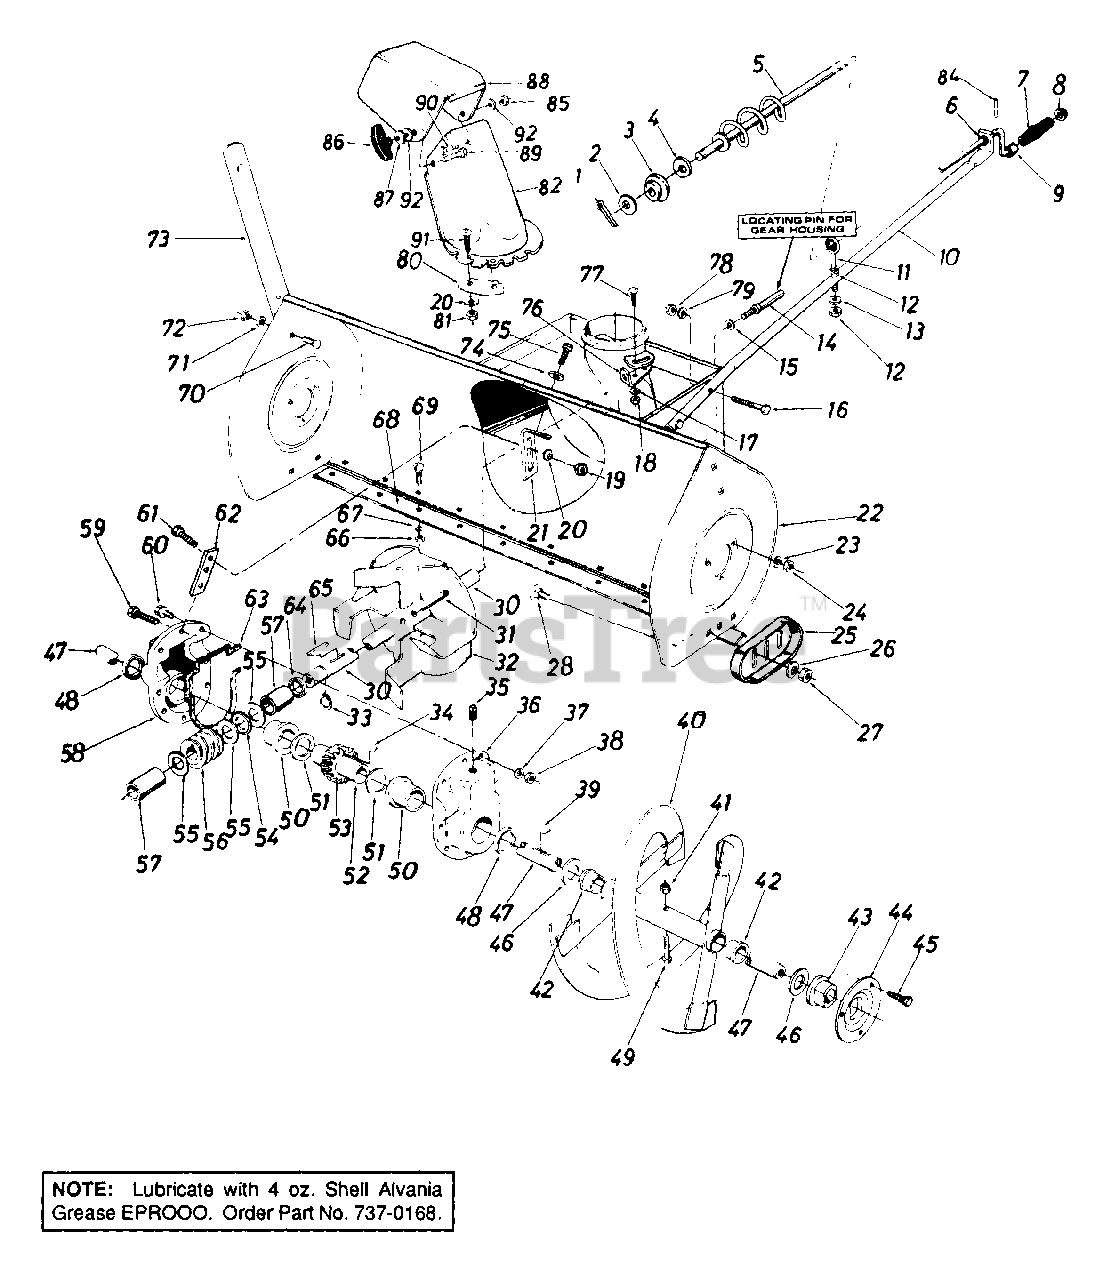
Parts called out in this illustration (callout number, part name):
1	Cotter Pin
2	Fl-Wash..39" I.D. x.62" O.D.
3	Plastic Bushing
4	Fl-Wash..385" I.D. x .62" O.D.
5	Chute Crank Ass'y.
6	Plastic Bushing
7	Knob (Black)
8	Push Nut 3/8" Rod
9	Spacer .385 I.D. x .50" I.D.
10	Chute Crank Support Tubing
11	Eyebolt
12	Hex Nut 5 16-18 Thd.
13	Bell-Wash..345" I.D. x.88" O.D.
14	Stud 3/8-16 x 2.75" Lg.
15	Bell-Wash..400" I.D. x .88" O.D.
16	Hex Bolt 3/8-24 x 1.25" Lg.
17	Bell-Wash..345" I.D. x .88" O.D.
18	Hex Nut 5/16-18 Thd.
19	Hex Nut 1/4-28 Thd.
20	Bell-Wash..265" I.D. x.75" O.D.
22	45" Snow Blower Housing Ass'y.
23	L-Wash. 5/16" I.D.
24	Hex Nut 5/16-18 Thd.
25	Slide Shoe
26	Bell-Wash..400" I.D. x .88" O.D.
27	Hex Jam Nut 3/8-16 Thd.
28	Carriage Bolt 3/8-16 x .62" Lg.
30	Blower Axle .875" Dia. x 14.75" Lg.
31	Spring Pin Spir. 5/16" Dia. x 1.75" Lg.
34	#91 Woodr-Key 1/4 x 3/4" Dia. (HDN)
35	Vent Plug
36	Comp. Gear Hsg. Half-L.H.
37	Spr-Wash..32" I.D. x .62" O.D.
38	Hex Ins. L-Nut 5/16-18 Thd.
39	#91 Woodr-Key 1/4 x 3/4" Dia. (HDN)
41	Hex ins. L-Nut 5/16-18 Thd.
42	Plastic Bushing
43	Flange Brg. w/flats 1" I.D.
44	Bearing Housing
45	Hex Sems Bolt 5/16-18 x .75" Lg.
46	Fl-Wash. 1.00" I.D. x 1.75" O.D.
47	Spiral Axle
48	Flange Bearing 1.503" I.D.
49	Shear Bolt 5/16-18 x 1.75" Lg.
50	Oil Seal 1.50" I.D.
51	Fl-Wash. 1.50" I.D. x 2.00" O.D.
52	Worm Gear Shaft
53	Double Threaded Worm Gear-L.H.
54	Thrust Brg. - 88" I.D. x 1.44" O.D.
55	Fl-Wash. .88" I.D. x 1.4" O.D.
56	Double Threaded Worm - L.H.
57	Sleeve
58	Complete Gear Hsg. Half - R.H.
59	Hex Bolt 5/16-18 x 1 25" Lg.
60	Hex Bolt 5/16-18 x 1.0" Lg. (Gr 5)
61	Hex Bolt 1/4-28 x .75" Lg.
62	Gear Housing Support Plate
63	Rubber Gasket
64	Oil Seal - .875" I.D.
65	#9 Hi-Pro Key 3/16 x 3/4" Dia (HT)
66	Hex Nut 5/16-18 Thd.
67	L-Wash. 5/16" I.D.
69	Carriage Bolt 5/16-18 x 1.00" Lg.
70	Carriage Bolt 5/16-18 x 62" Lg.
71	L-Wash. 5/16" I.D.
72	Hex Nut 5/16-18 Thd.
73	Guide Blade
74	Bell-Wash..345" I.D. x .88" 0.D.
75	Hex Wash. Hd. AB Tap Scr 5/16 x .75" Lg.
77	Carriage Bolt 5/16-18 x .75" Lg.
78	Hex Ins. L-Nut 3/8-24 Thd.
79	L-Wash. 3/8 I.D.
80	Chute Flange Keeper
81	Hex Nut 1/4-20 Thd.
82	Chute Ass'y. w/Chute Guard
84	Bell-Wash..345" I.D. x .88" O.D.
85	Hex Cent. L-Nut 5/16-18 Thd.
86	Knob Handle
87	Bell-Wash..345" I.D. x 88" O.D.
88	Top Chute Ass'y.
89	Carriage Bolt 5/16-18 x 1 00" Lg.
90	Carriage Bolt 5/26-18 x 62" Lg.
91	Truss Mach. Scr. 1/4-20 x .75"
92	Roll Pin .12 Dia. x .63"
